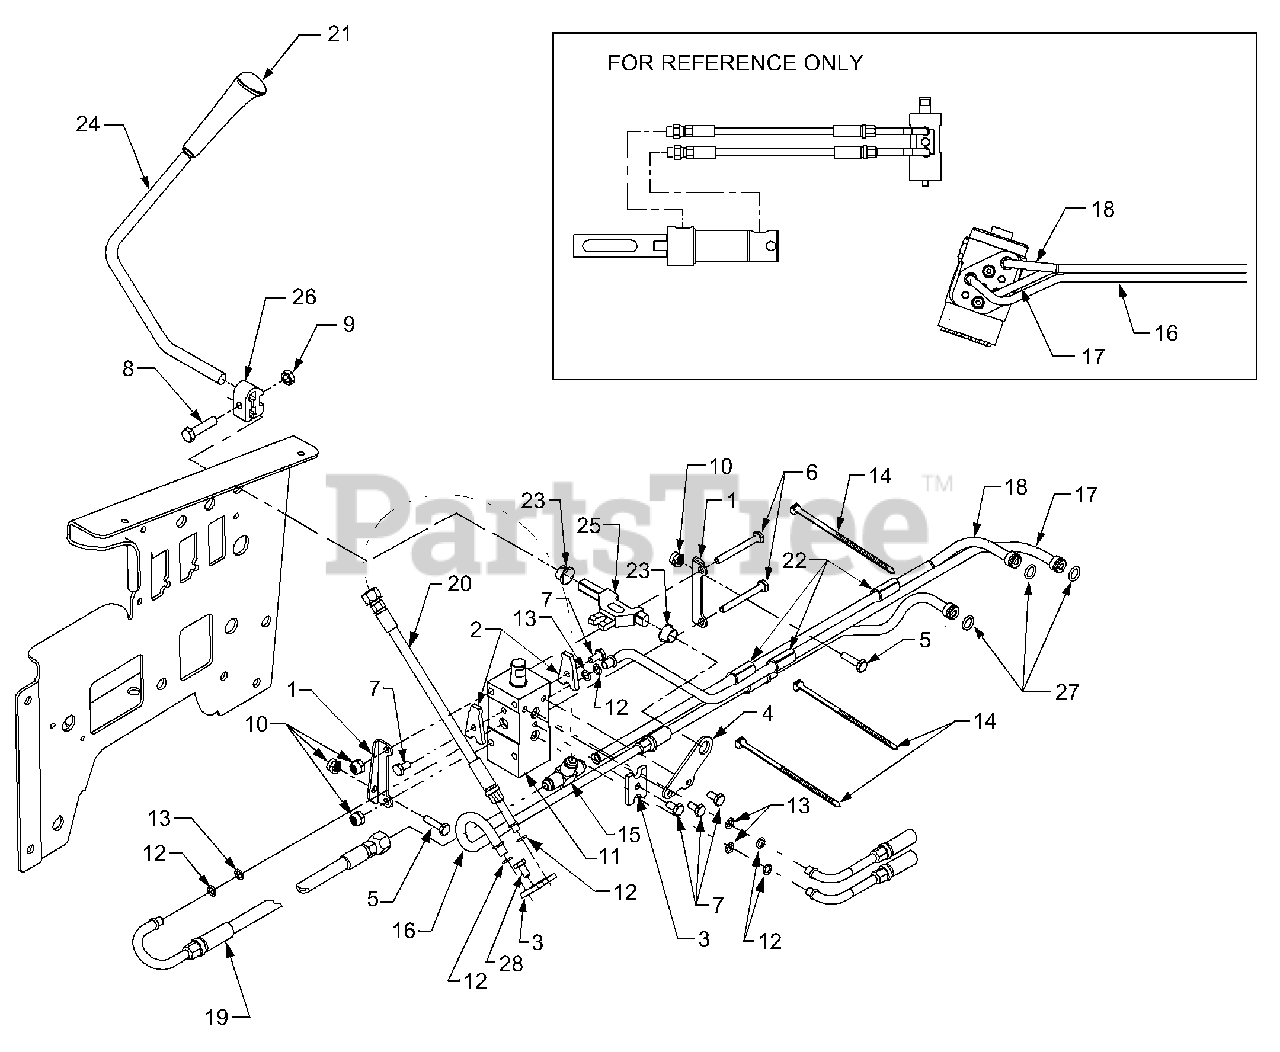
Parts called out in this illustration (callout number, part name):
1	Bracket, Valve Mounting
2	Clamp, Side Valve
3	Clamp, Double Valve
5	Screw, Hex Cap 1/4-20 x 1.0 GR5
6	Screw, Hex Cap 1/4-20 x 2.25 GR5
7	Screw, Hex Cap 1/4-20 x .50 GR5
8	Screw, Hex Cap 5/16-18 x 1.375 GR5
9	Nut, Hex Insert Lock, 5/16-18
10	Nut, Hex Flange Lock, 1/4-20
11	Valve, Hydraulic
12	O-Ring, Backup
13	O-Ring
14	Cable Tie
15	T-Fitting, 9/16-18 Thrd
16	Tube, Hydraulic (Pump to Strng)
17	Tube, Hydraulic (Aux. from Strng)
18	Tube, Hydraulic (Strng Return)
19	Tube, Hydraulic (Aux Return)
20	Tube, Hydraulic (Return to Pump)
21	Knob, Lift
22	Rubber Spacer
23	Bearing, Nylon Flange
24	Handle, Center Lift Valve
25	Link, Lift
26	Clamp, Handle
27	O-Ring, .426 x .566 x .070
28	Screw, Hex Cap 1/4-20 x .62 GR5
